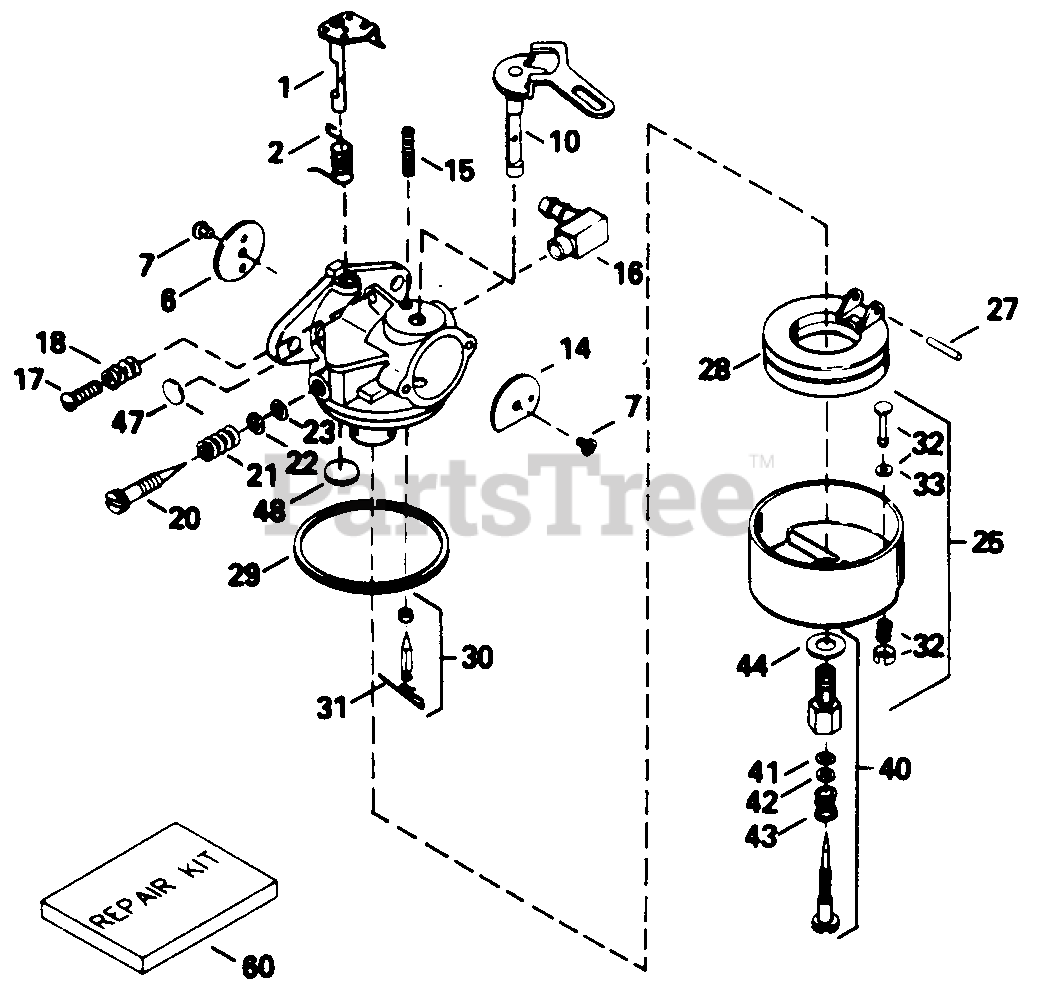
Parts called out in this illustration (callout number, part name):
1	Throttle Shaft & Lever Ass'y.
2	Throttle Return Spring
6	Throttle Shutter
7	Throttle & Choke Shutter Screw
10	Choke Shaft & Lever Ass'y.
14	Choke Shutter
15	Choke Positioning Spring
16	Fuel Fitting
17	Idle Speed Screw
18	Tension Spring
20	Idle Mixture Screw
21	Idle Tension Spring
22	Washer, Idle Screw
23	O-Ring, Idle Screw
25	Float Bowl Ass'y.
27	Shaft, Float
28	Float
29	O-Ring, Float Bowl to Body
30	Inlet Needle, Seat & Clip
31	Spring Clip
32	Bowl Drain Ass'y.
33	Drain Plunger Gasket
40	Main Adj. Screw Ass'y.
41	O-Ring, High Speed Mixture Screw
42	Washer, High Speed Mixture Screw
43	Tension Spring, High Speed Mixture Screw
44	Bowl Nut Washer
47	Welch Plug, Idle Mixture Well
48	Welch Plug, Atmospheric Vent
60	Repair Kit
